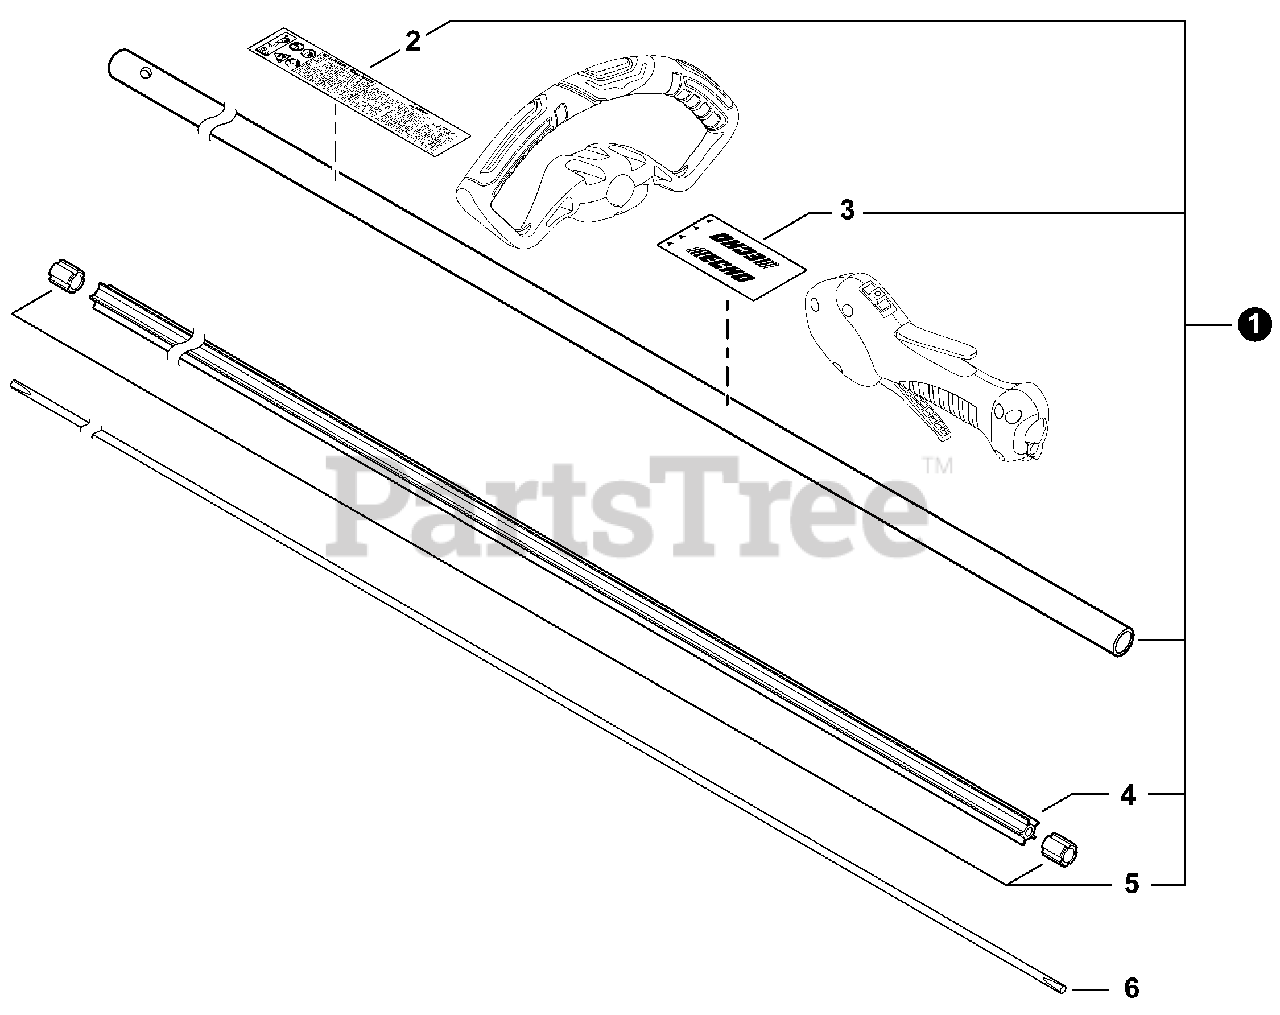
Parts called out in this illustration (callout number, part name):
1	MAIN PIPE ASSY
2	LABEL, CAUTION
3	LABEL, HANDLE LOCATION
4	LINER, FLEXIBLE 21.6×1420
6	DRIVESHAFT - FLEXIBLE
